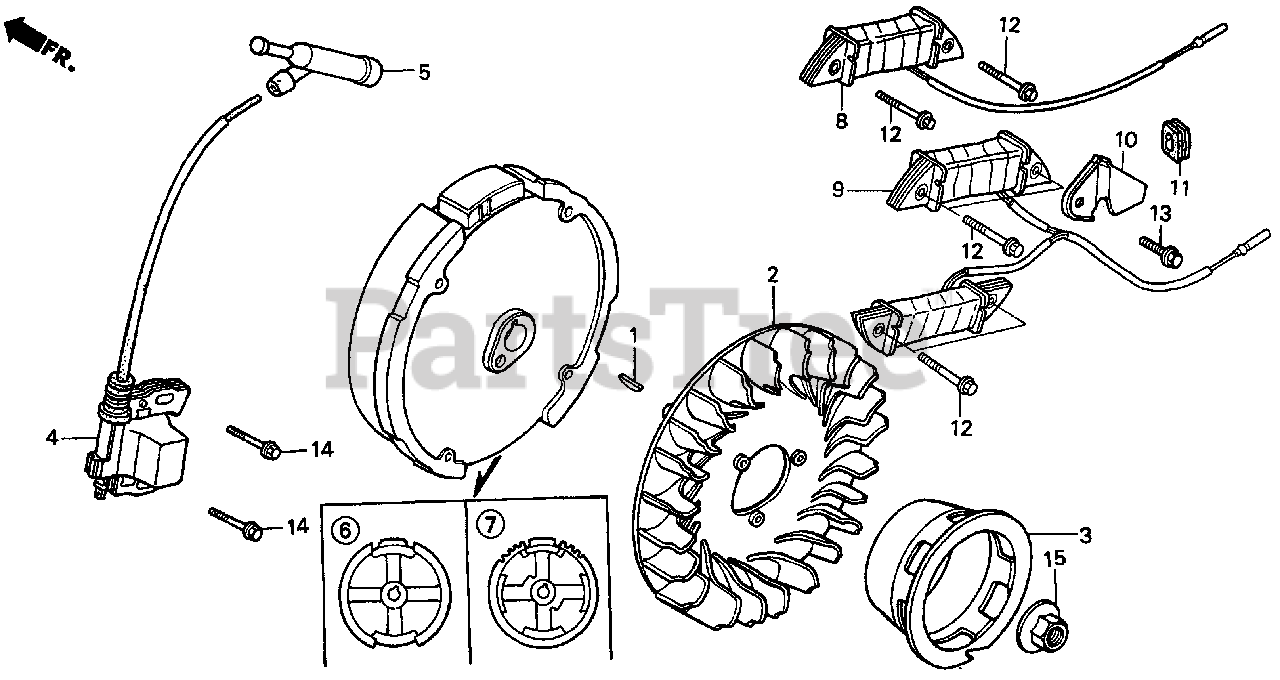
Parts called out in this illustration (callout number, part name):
1	KEY, SPECIAL WOODRUFF (25X18)
2	FAN, COOLING
3	PULLEY, STARTER
4	COIL ASSY., IGNITION
5	CAP ASSY., NOISE SUPPRESSOR (NICHIWA Y-EZ RTFM256)
6	FLYWHEEL (LAMP)
9	COIL ASSY., LAMP (12V/50W)
10	CLAMP, WIRE
11	GROMMET, WIRE
12	BOLT, FLANGE (6X28)
13	BOLT, FLANGE (5X10)
14	BOLT, FLANGE (6X25)
15	NUT, SPECIAL (14MM)
